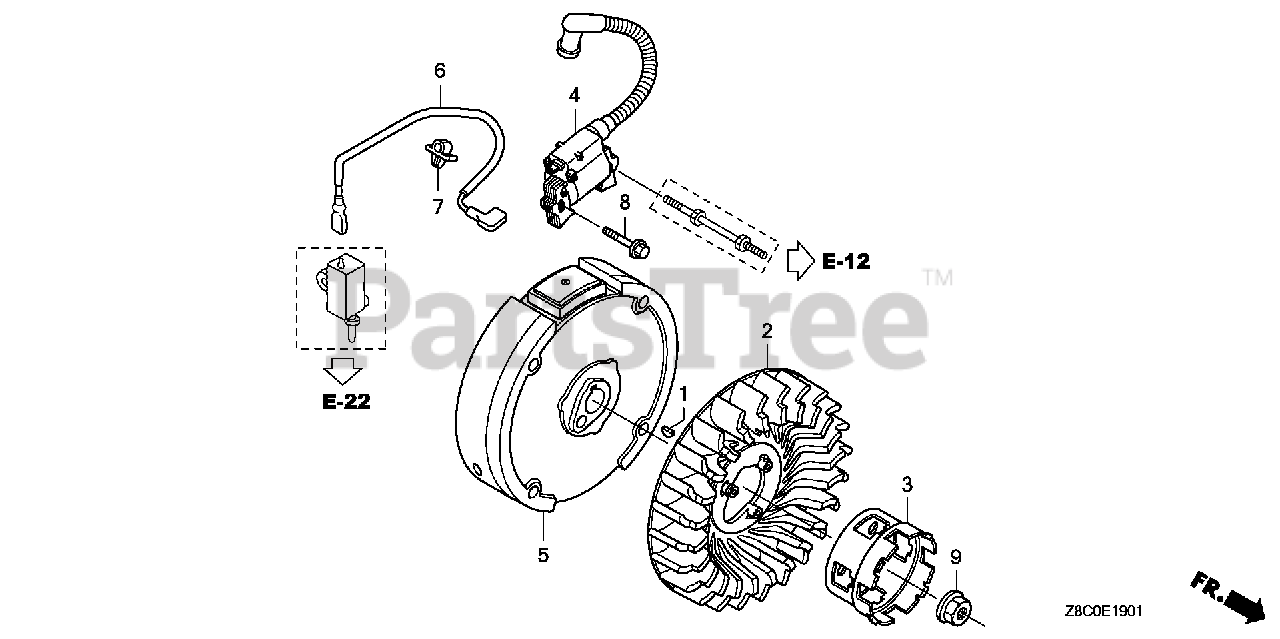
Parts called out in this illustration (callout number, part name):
1	KEY, SPECIAL WOODRUFF (25X18)
2	FAN, COOLING
3	PULLEY, STARTER
4	COIL ASSY., IGNITION (TOYO)
4	COIL ASSY., IGNITION (PHELON)
5	FLYWHEEL
8	BOLT, FLANGE (6X23) (CT200)
9	NUT, SPECIAL (14MM)
